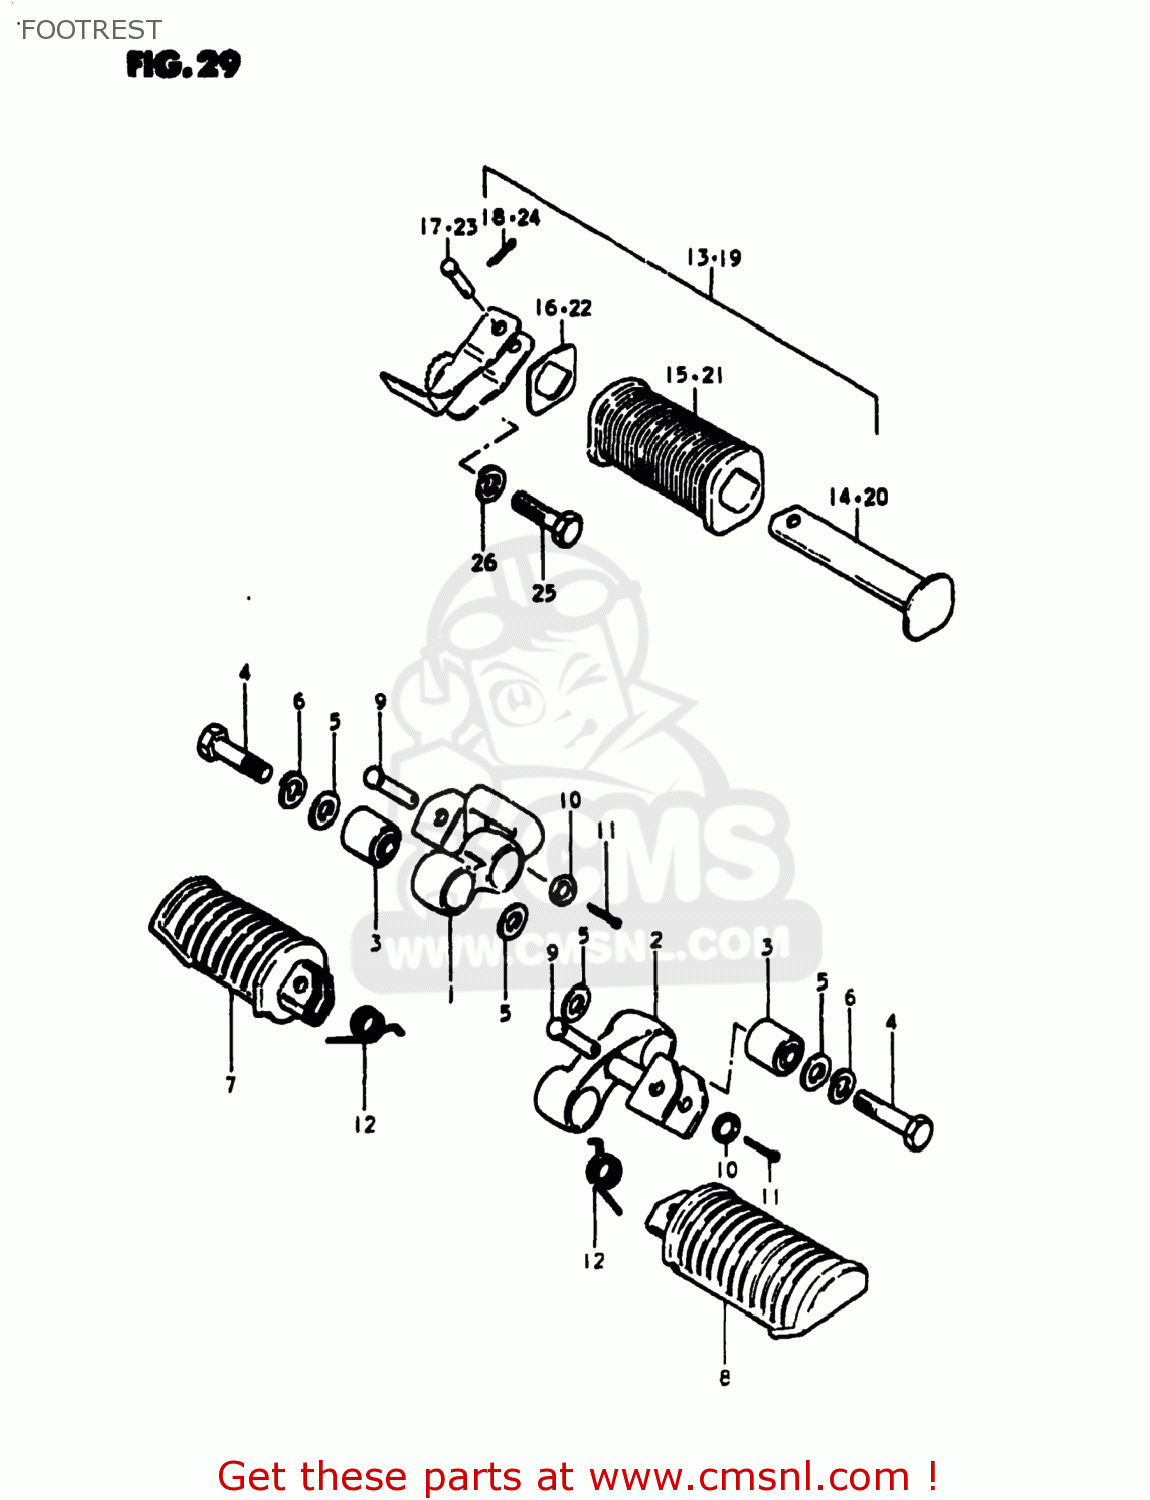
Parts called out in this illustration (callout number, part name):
1	BAR,FRONT FOOTREST
2	BAR,FRONT FOOTREST,LEFT
3	BUSH
4	BOLT
5	WASHER (10.1X21X2.3)
6	LOCK WASHER
7	RUBBER,FRONT FOOTREST
8	FOOTREST
9	PIN
10	WASHER
11	PIN
12	SPRING
13	FOOTREST ASSEMBLY,REAR
14	BAR,REAR FOOTREST
15	RUBBER, LH
16	WASHER,REAR FOOTREST RUBBER
17	PIN
18	PIN
19	FOOTREST ASSEMBLY,REAR
20	BAR,REAR FOOTREST,LEFT
21	RUBBER,PILLION FOOTREST
22	WASHER,PILLION FOOTREST RUBBER
23	PIN
24	PIN
25	BOLT 10X30
26	LOCK WASHER
